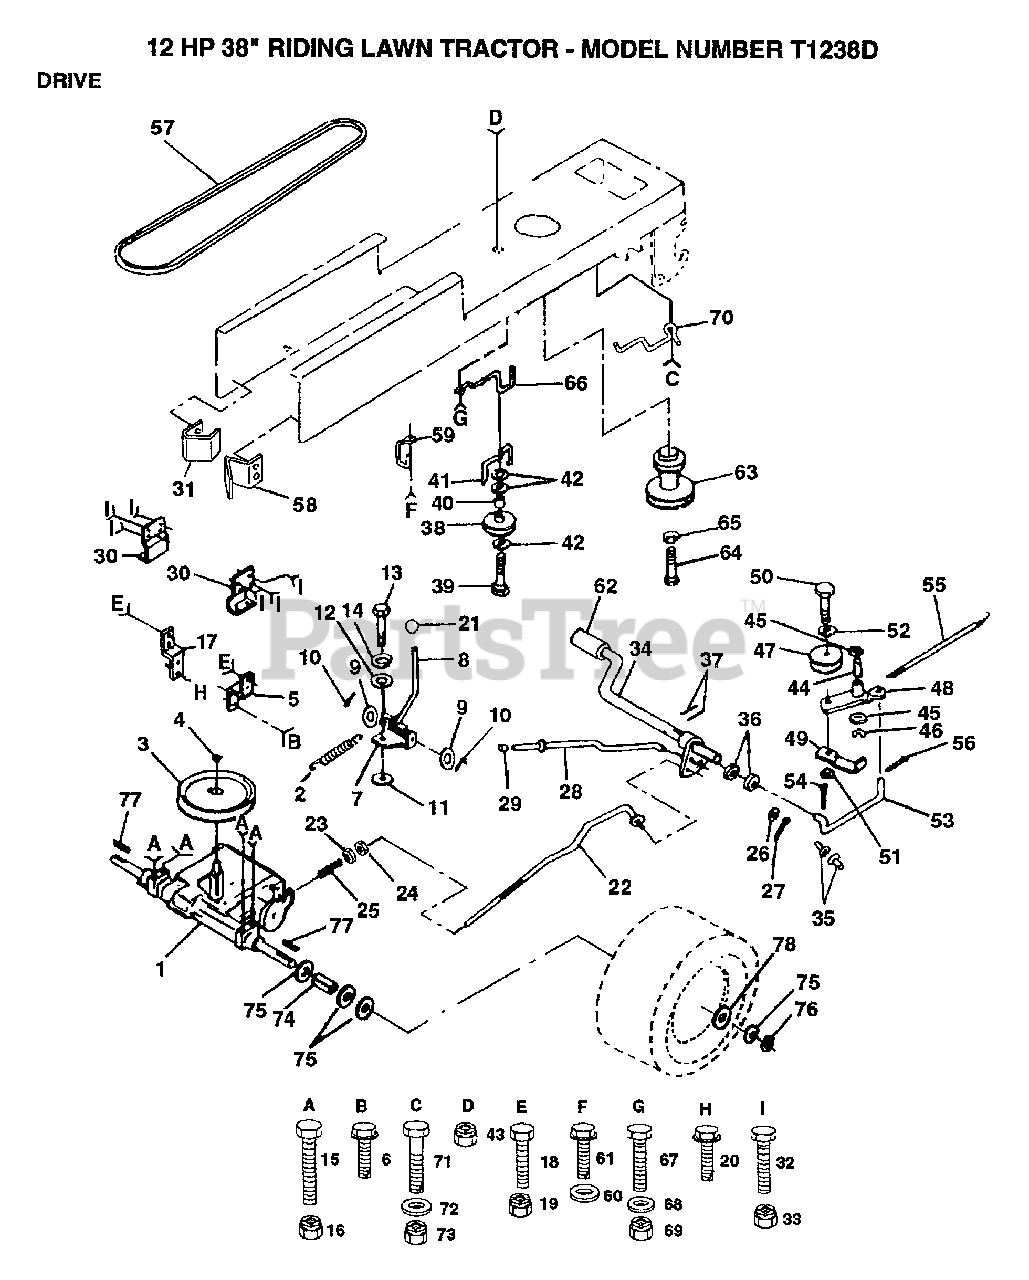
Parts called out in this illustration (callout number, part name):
3	PULLEY TRANS
5	STRAP TORQUE
6	SCREW
7	PLATE SHIFT LT
8	ROD SHIFTER
9	WASHER
10	PIN COTTER 1/8
11	WASH-SHFT PLT LT
12	WASHER LT
14	LOCKWASHER
15	BOLT
17	STRAP TORQUE
20	SCREW
21	CONTROL KNOB LT
23	NUT
24	NUT
25	SPRING ROD LT
26	WASHER
27	COTTER PIN
28	PARKING BRAKE ROD
30	BRACKET LT
31	"KEEPER,BELT LH T"
35	NYLON BEARING
36	WASHER LT
38	PULLEY.IDLER.FLAT
39	BOLT
40	SPACER T
41	BELT KEEPER LT
42	WASHER
44	"LY, BEARING"
45	WASHER LT
46	KLIP RING
48	ARM IDLER
49	RETAIN BELT
52	WASHER
53	"LINK, CLUTCH T"
54	COTTER PIN
55	"SPRING, RETURN LT"
56	COTTER PIN
57	BELT-V.90.0.GD.DR
58	"KEEPER,BELT RH T"
60	WASHER
61	SCREW
62	PEDAL COVER T
65	LOCKWASHER
66	KEEPER.BELT.ENG.L
67	BOLT
68	WASHER
70	GUIDE BLT DR MWR
71	BOLT
72	WASHER
74	SPACER LT
75	WASHER
76	E-RING LT
77	SQUARE KEY
78	WASHER
